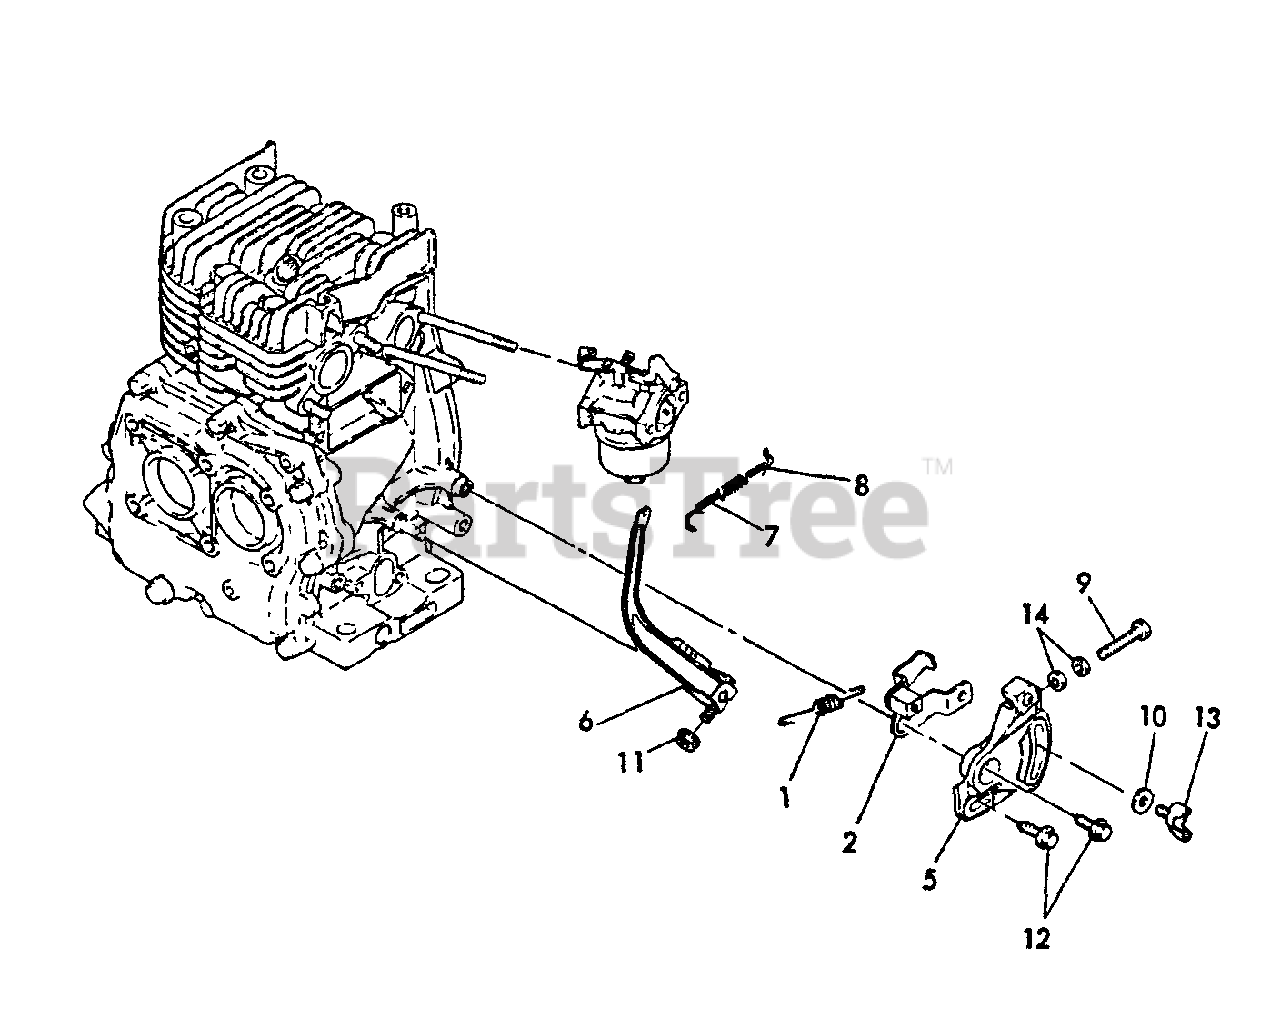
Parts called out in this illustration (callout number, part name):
1	SPRING, REGULATOR
2	HANDLE ASSY, REGULATOR
5	BRACKET, REGULATOR
6	LEVER, GOVERNOR
7	LINK, THROTTLE
8	SPRING, TENSION
9	BOLT
10	WASHER - 6
11	U-NUT M6
12	BOLT - 6×20
13	THUMBSCREW - 6×15
14	LOCKNUT - 6 -- PLATED
